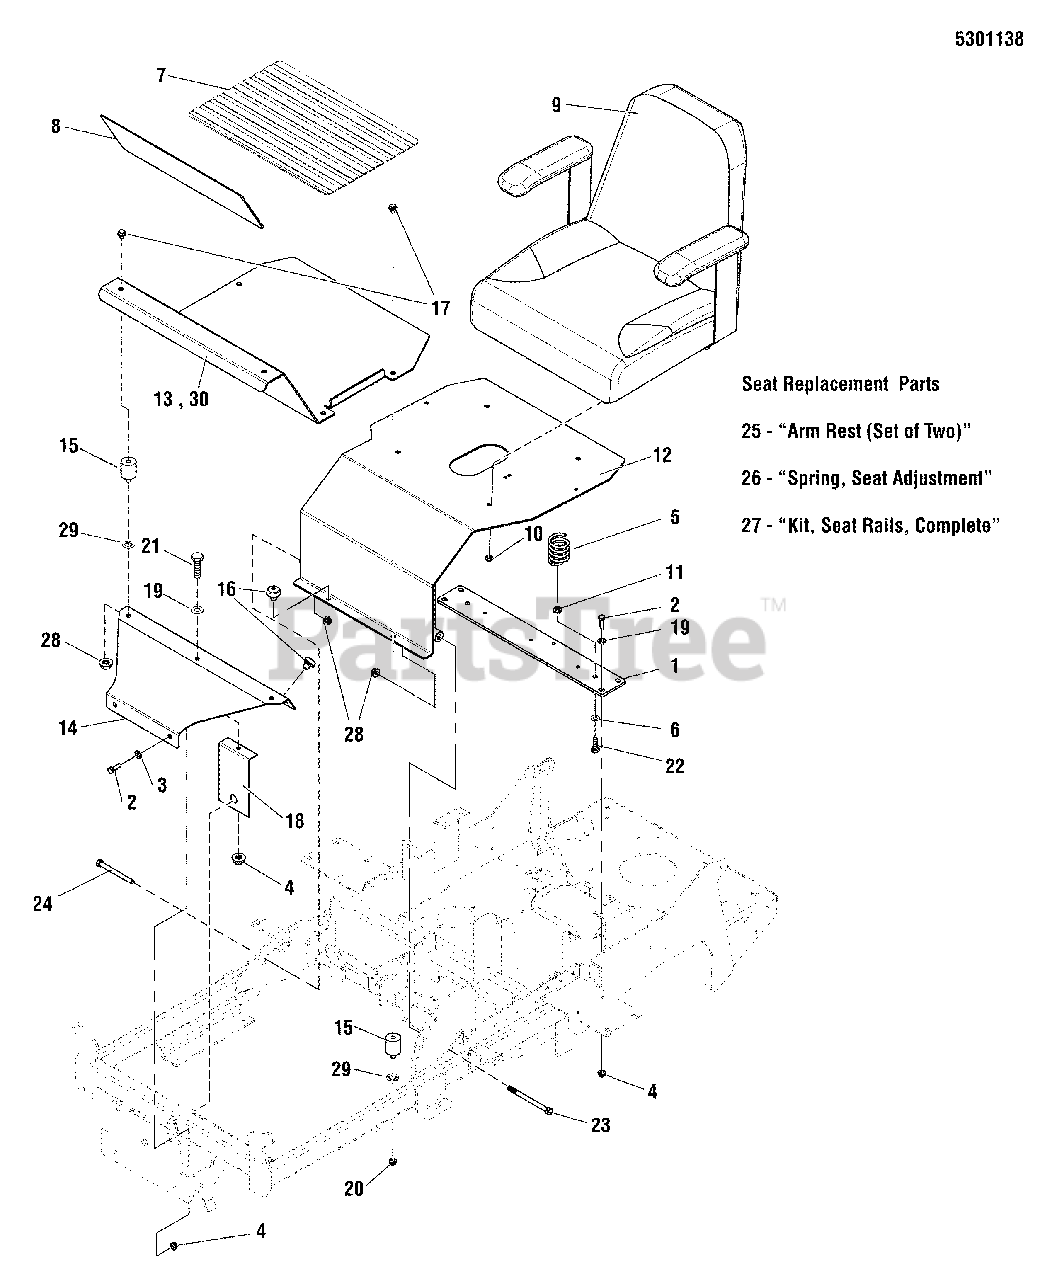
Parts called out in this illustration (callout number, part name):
1	MOUNT, OIL FILTER - ORG
2	BOLT, 5/16-18 X 1 GD5 YZ
3	WASHER, 5/16 GD.9 FLAT
4	NUT, 5/16-18 HEX NYLOCK FLANGE
5	SPRING, SEAT SUPPORT
6	WASHER, 3/8 SAE
7	SAFETY WALK, FLOOR PLATE, 17.13 X 11.50
8	SAFETY WALK, FLOOR REST, 17.13 X 6.00
9	SEAT, XB-180, NO LOGO, BLACK
10	NUT, 5/16-18 HEX NYLON LOCK
11	NUT, 3/8-16 HEX NYLOCK FLANGE
12	WELD, SEAT PLATE - ORG
13	PLATE, FLOOR, CONSUMER Z - ORG
14	PLATE, FLOOR, FRONT, CONS Z
15	MNT, VBRTN, 30 DURO
16	MNT, VBRTN, RBBR
17	BOLT, 3/8-16 X 5/8, SERRATED UNDER HEAD
18	PLATE, SUPPORT, FRONT FLOOR
19	WASHER, 5/16 SAE
20	NUT, 3/8-16 HEX SERRATED FLANGE
21	BOLT, 5/16-18 X 3/4 GD5
22	BOLT, 3/8-16 X 1 GD5 YZ
23	BOLT, 3/8-16 X 5" GD5 YZ
24	BOLT, 3/8-16 X 4 GD5 YZ
25	ARM REST, SET OF TWO (SV)
26	SPRING, EXTENSION, SEAT ADJUSTMENT (BLK OR SLVR)
27	KIT, SEAT RAILS. COMPLETE (SV)
28	NUT, 3/8-16 HEX NYLOCK FLANGE
29	WASHER, 3/8" ID, INTERNAL TOOTH
30	PLATE, FLOOR, CONSUMER Z - ORG
